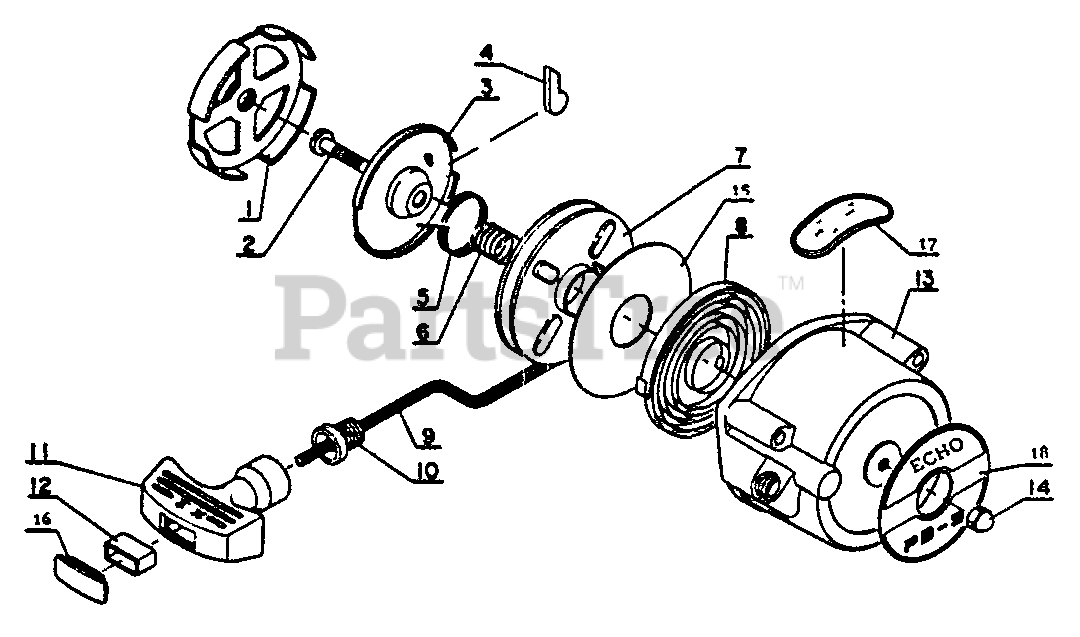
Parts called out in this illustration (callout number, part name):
1	PAWL CATCHER
3	PLATE, FRICTION
4	RATCHET
5	SPRING
6	SPRING
7	REEL, ROPE
8	SPRING, RECOIL
9	ROPE, STARTER 4.0×880
10	GUIDE, ROPE
11	GRIP, STARTER
12	RING, RETAINING
13	CASE, STARTER
14	NUT - 5 -- CAP
15	PLATE, STARTER
16	COVER, HANDLE
17	LABEL - CAUTION
18	LABEL - MODEL
